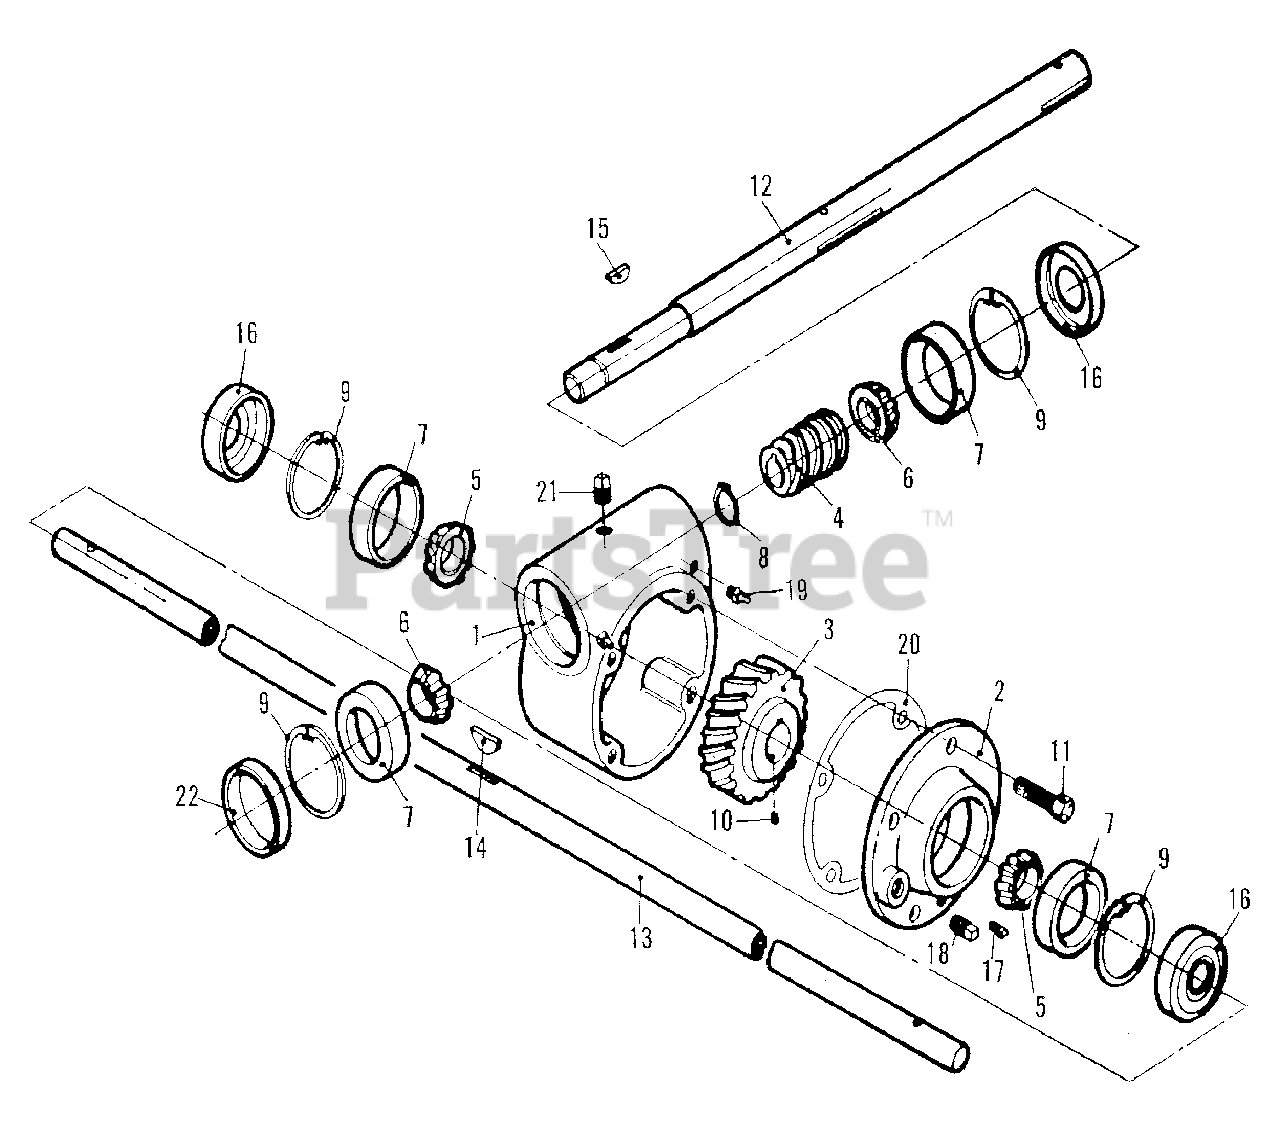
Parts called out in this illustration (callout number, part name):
1	HOUSING, Gear
2	COVER, Gear
5	CONE, Bearing (#15126)
6	CONE, Bearing (#15101)
7	CUP, Bearing, (#15245)
8	RING, Retaining, External
9	RING, Retaining, Internal
10	SETSCREW, Worm Gear
11	CAPSCREW, 3/8NC x 3/4
12	SHAFT ASSEMBLY, Input
13	SHAFT ASSEMBLY, Output (60")
14	KEY, Woodruff, Hard (No. 18)
15	KEY, Woodruff, Hard ("A")
16	SEAL, Shaft Cover
17	PLUG, Pipe, 1/8NPT
18	PLUG, Level, 3/8NPT
19	FITTING, Grease
20	GASKET, Cover
21	PLUG, Vent, 3/8NPT
22	CAP, Input Bearing
